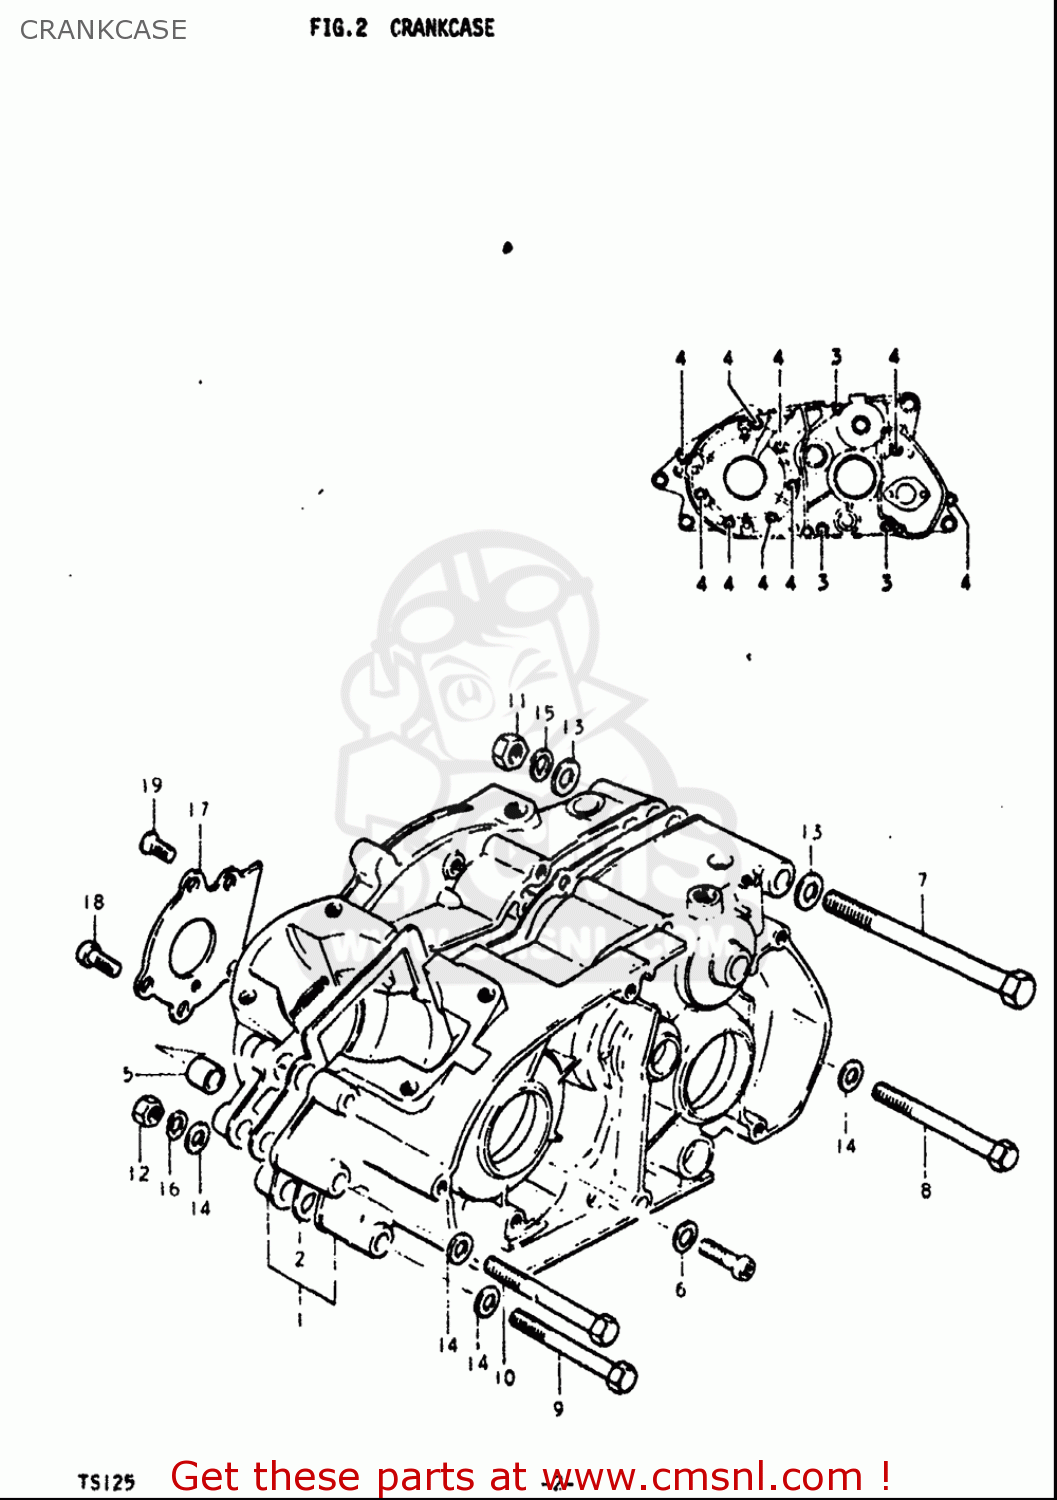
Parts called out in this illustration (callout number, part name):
2	GASKET,CRANKCASE (NAS)
3	SCREW
4	SCREW
5	PIN
6	WASHER
7	BOLT(10X120)
8	BOLT
9	BOLT
10	BOLT
11	NUT
12	NUT
13	WASHER
14	WASHER
15	WASHER,LOCK
16	WASHER,LOCK
18	SCREW
19	SCREW
